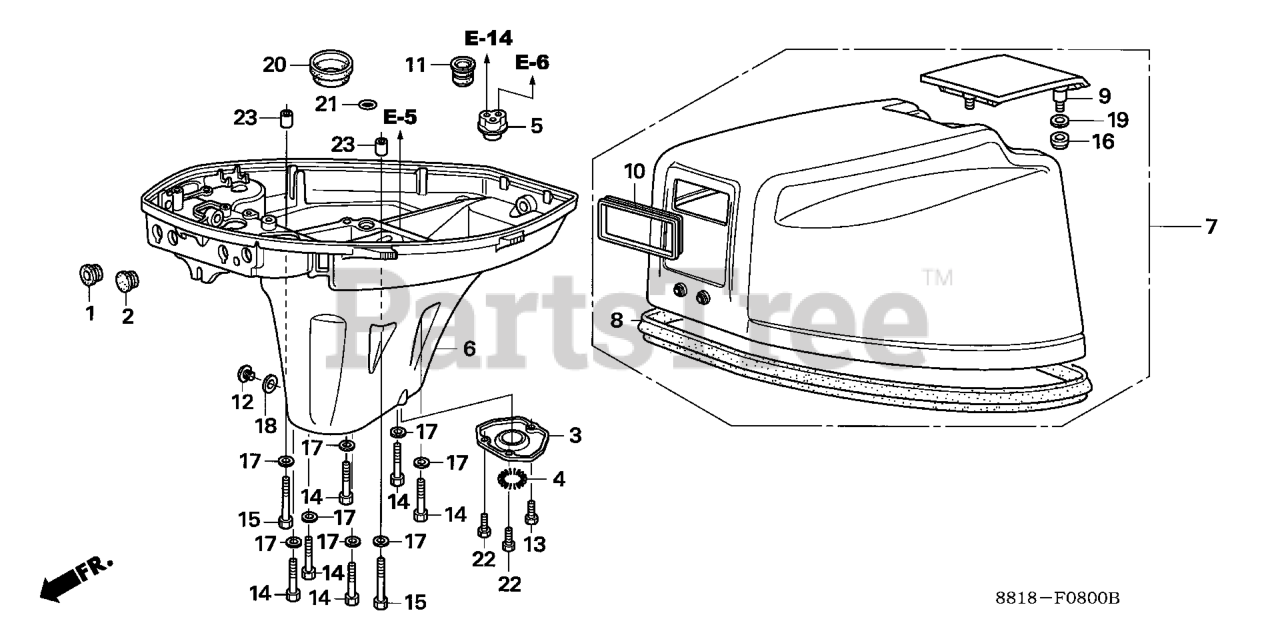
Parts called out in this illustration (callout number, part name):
1	GROMMET A, WIRE
2	GROMMET C, OIL CASE
3	PLATE, EX.
4	BAND, EX. SEAL
5	MANIFOLD, TUBE
6	CASE, OIL *NH282MU* (OYSTER SILVER METALLIC-U)
7	COVER, ENGINE *NH282MU* (OYSTER SILVER METALLIC-U)
8	SEAL, ENGINE COVER
9	HANDLE, TILT
10	SEAL, RECOIL
11	GROMMET, WATER CHECK
12	BOLT, OIL CHECK
12	BOLT, OIL CHECK (8X8)
13	BOLT, HEX. (6X12)
14	BOLT, HEX. (6X32)
15	BOLT, HEX. (6X40)
16	NUT (6MM)
17	WASHER, PLAIN (6MM) Use up to Frame SN 4800342.
18	WASHER, NYLON (8MM)
19	WASHER (6MM)
20	SEAL, COUPLING (25X40X22)
21	O-RING (9.8X1.9)
22	BOLT, HEX. (6X12)
23	PIN A, DOWEL (8X14)
